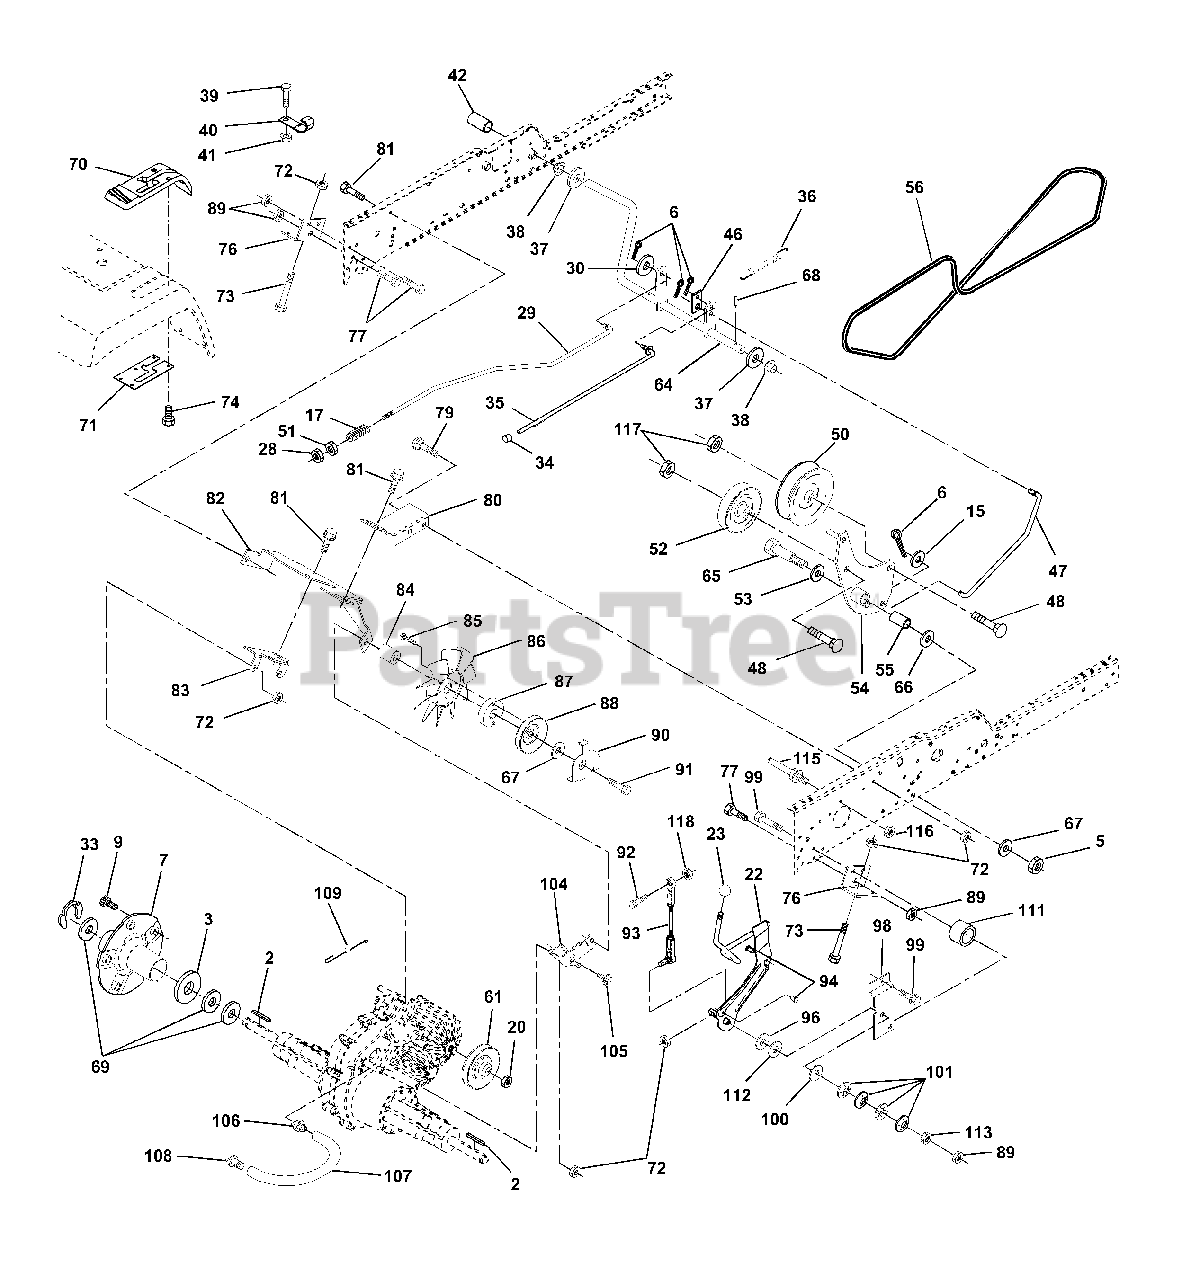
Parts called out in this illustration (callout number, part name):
2	Key 1/4 x 2.5
3	Washer Thrust Axle Harden
5	Nut Crownlock 3/8-16
6	Pin Cotter 1/8 x 3/4
7	Wheel Hub Asm.
9	Bolt Hub
15	Washer 13/32 x 13/16 x 16 Ga.
17	Spring Rod Brake
20	Nut Hex Jam Toplock 1/2-20
22	Shaft Arm Asm
23	Knob
28	Nut, Hex Jam 3/8-16
29	Brake Rod
30	Washer 13/32 x 1 x 14Ga
33	Ring E
34	Cap Plunger
35	Rod Parking Brake
36	Spring Extension
37	Washer 25/32 x 1-1/4 x 16 Ga.
38	Nyliner
39	Screw Fin #10-24 x 1
40	Actuator Interlock Switch
41	Nut Toplock #10-24 Unc
42	Cover Pedal
46	Retainer Spring
47	Clutch Rod
48	Bolt Carriage 3/8-16 x 1-1/2 Gr. 5
50	Pulley Idler Flat
51	Nut, Crownlock 3/8-16
52	Pulley Idler Grooved
53	Washer Hartdened
54	Arm Asm Idler Clutch 98
55	Bearing, Idler
56	V-Belt
58	Screw 3/8-16 x 1-1/2
61	Pullery Transaxle
64	Shaft Asm Brake Parking Clutch
65	Bolt Shoulder
66	Washer Hardened
67	Washer 13/32 x 13/16 x 12 Ga
68	Pin Roll
69	Washer
70	Console Hydro Fender
71	Plate Console Shift
72	Locknut Hex W/Washer Insert
73	Bolt Hex Flghd 5/16-18 x 3 Gr. 5
74	Screw, Hex Wsh Hi-Lo 1/4-1/2
76	Bracket Transaxle
77	Bolt Fin Hex 7/16-14 x 1
79	Bolt Carriage 5/16-18 x 5/8
80	Bracket Torque RH
81	Screw 3/8-16 x 3/4
82	Bracket Mount Torque/Fan
83	Strap Torque Mid
84	Spacer
85	Screw #10-24 x 1-1/4
86	Fan 7" Hydro
87	Adapter Fan
88	Pully Idler V-Groove Flange
89	Nut, Crownlock 7/16-14
90	Keeper Belt
91	Screw Thdrol 3/8-16 x 2-3/4
92	Bolt Fin Hex 5/16-18 x 1.75
93	Link Shift Asm
94	Fastner Christmas Tree
96	Washer Nickel Plated
98	Bracket Shift
99	Screw 3/8-16 x 1-1/2
100	Washer Compression
101	Washer Bellville
104	Bracket Idler
105	Screw Tap 1/4-20 x 1/2
106	O-Ring Asm Hydro Gear
107	Line Fuel Hydro 15" VGT Serv
108	Cap Asm Vent Hydro Gear
109	Spring Return Brake
111	Spacer Shift Lever VGTH
112	Washer Nylon High Temp
113	Nut Hex ASF 7/16-14 Unc
115	Keeper Belt T/A GND DR LR
116	Nut Lock Hex Flange 5/16-18
117	Nut Lock Flg. 3/8-16 Unc
